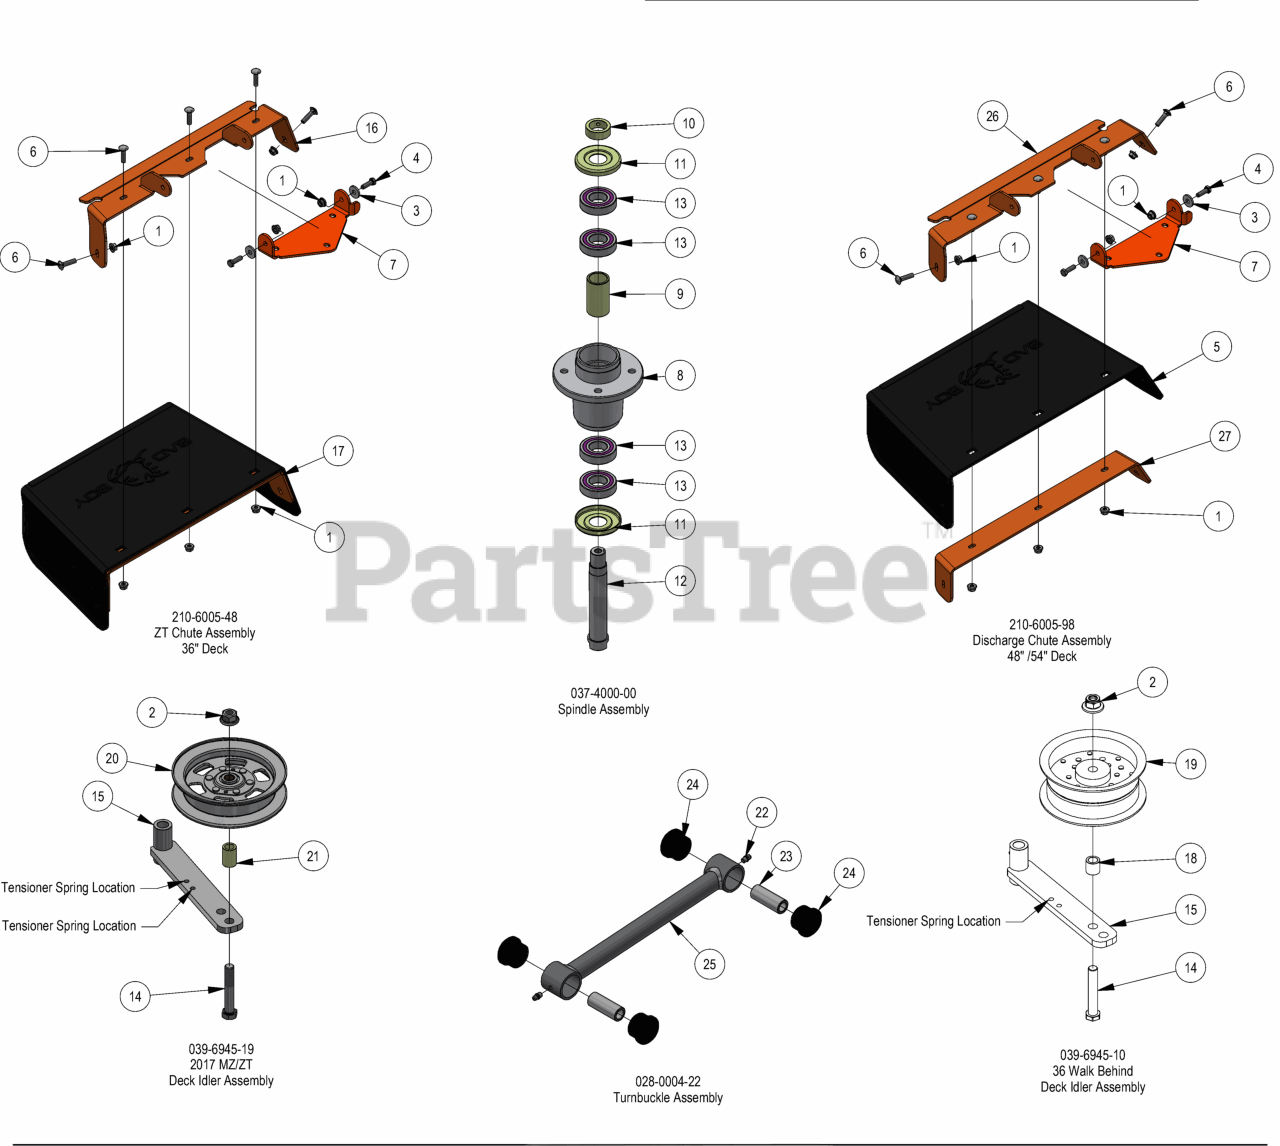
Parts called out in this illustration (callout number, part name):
1	5/16-18 NYLON INSERT FLANGE LOCKNUT ZINC
2	1/2-13 NYLON INSERT FLANGE LOCKNUT ZINC
3	.360 ID X .983 OD X .120 THICK FLAT WASHER NYLON
4	5/16-18 X 1 HEX CAP SCREW (GR.5) ZINC
5	Rubber Discharge Chute
6	5/16-18 X 1-1/4 CARRIAGE BOLT ZINC
7	Discharge Chute Hanger (deck mounted)
8	4000 Series Spindle Housing
9	4000 Series Spindle Spacer
10	Locking Collar w/ 1/4"-20 Set Screw
11	Spindle Dust Cap
12	Spindle Shaft
13	Bearing - 6206
14	1/2-13 x 3 GR5 Hex Bolt Zinc
15	Deck Idler
16	Discharge Upper Chute Bracket
17	Discharge Lower Chute Bracket
18	Spacer 3/4 OD x 1/2 ID x 3\4 Length
19	5 3/4" Deck Idler Pulley
20	5" Idler Pully
22	1/4-28 Grease Fitting
23	2018 Maverick Bushing Sleeve
24	2018 Maverick Bushing
25	2022 Isolator Turnbuckle Body
26	60" Discharge Chute Upper Hanger
27	60" Discharge Lower Bracket
